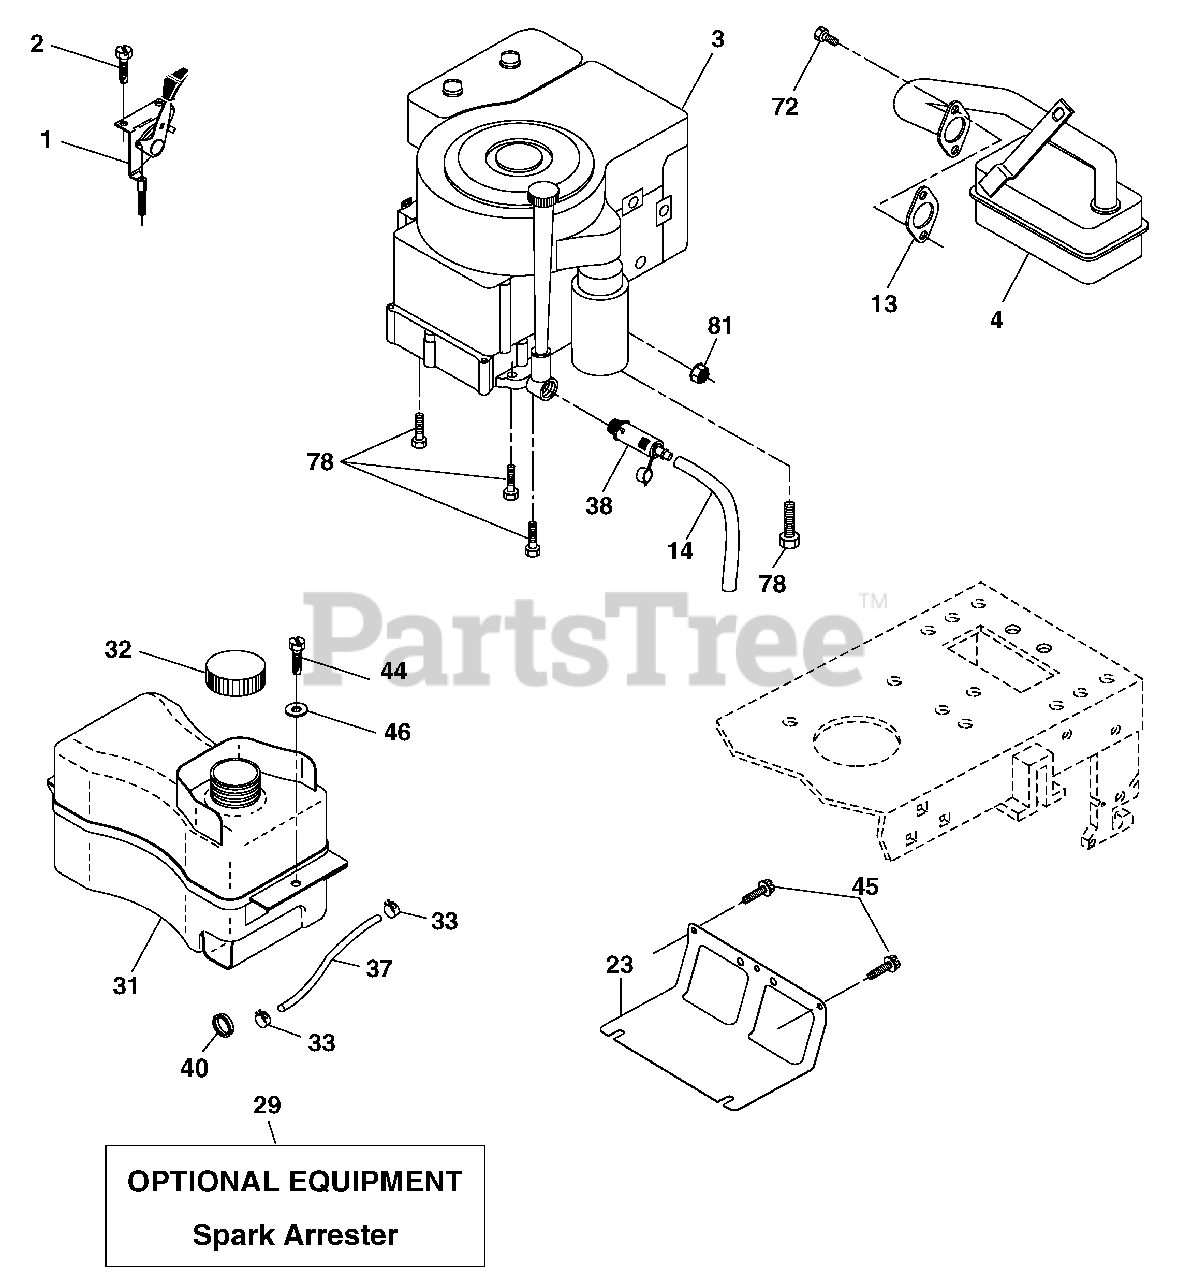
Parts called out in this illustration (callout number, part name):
1	Control Th/ch Flag
2	Screw Hex Thd Cut 1/4-20 x 1/2
4	Muffler Exhaust B&S
13	Gasket Eng 1 313 Id Tin Plated
14	Tube Drain Oil Easy
23	Shield BRN/DBR Guard
29	Kit Spark Arrestor (Flat Scrn)
31	Tank Fuel Front
32	Cap Asm Fuel
33	Clamp Hose
37	Line Fuel
38	Plug Drain Oil
40	Bushing Snap Nyl Blk Fuel Line
44	Screw Thdrol 1/4-20 x 3/4
45	Screw Hex Wsh Thdrol 3/8-16
46	Washer 9/32 x 7/8 x 16 Ga.
72	Screw Socket Head 5/16-18 x 3/4
78	Screw 3/8-16 x 1-1/4
81	Nut Keps Hex 1/4-20 unc
